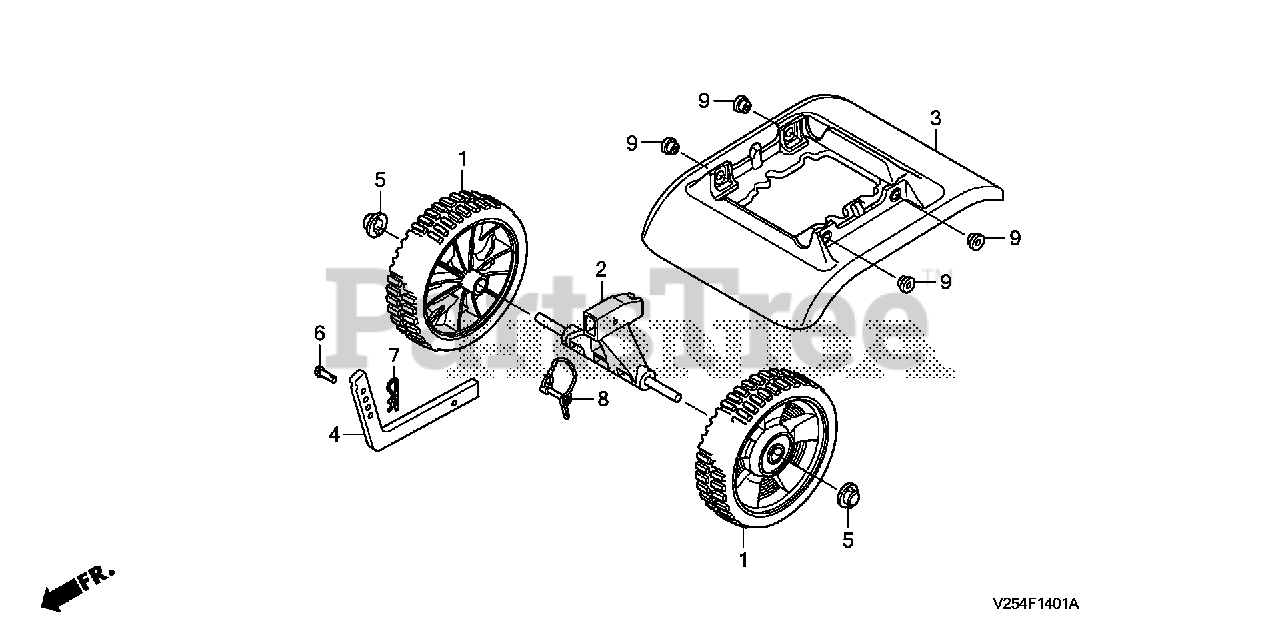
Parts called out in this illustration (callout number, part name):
1	WHEEL, RR.
2	BAR, WHEEL
3	FENDER, FR.
5	NUT, PUSH (9.53MM)
7	PIN, LOCK (6.35MM)
8	LINCHPIN (1/4X1-3/8")
9	COLLAR, FENDER
